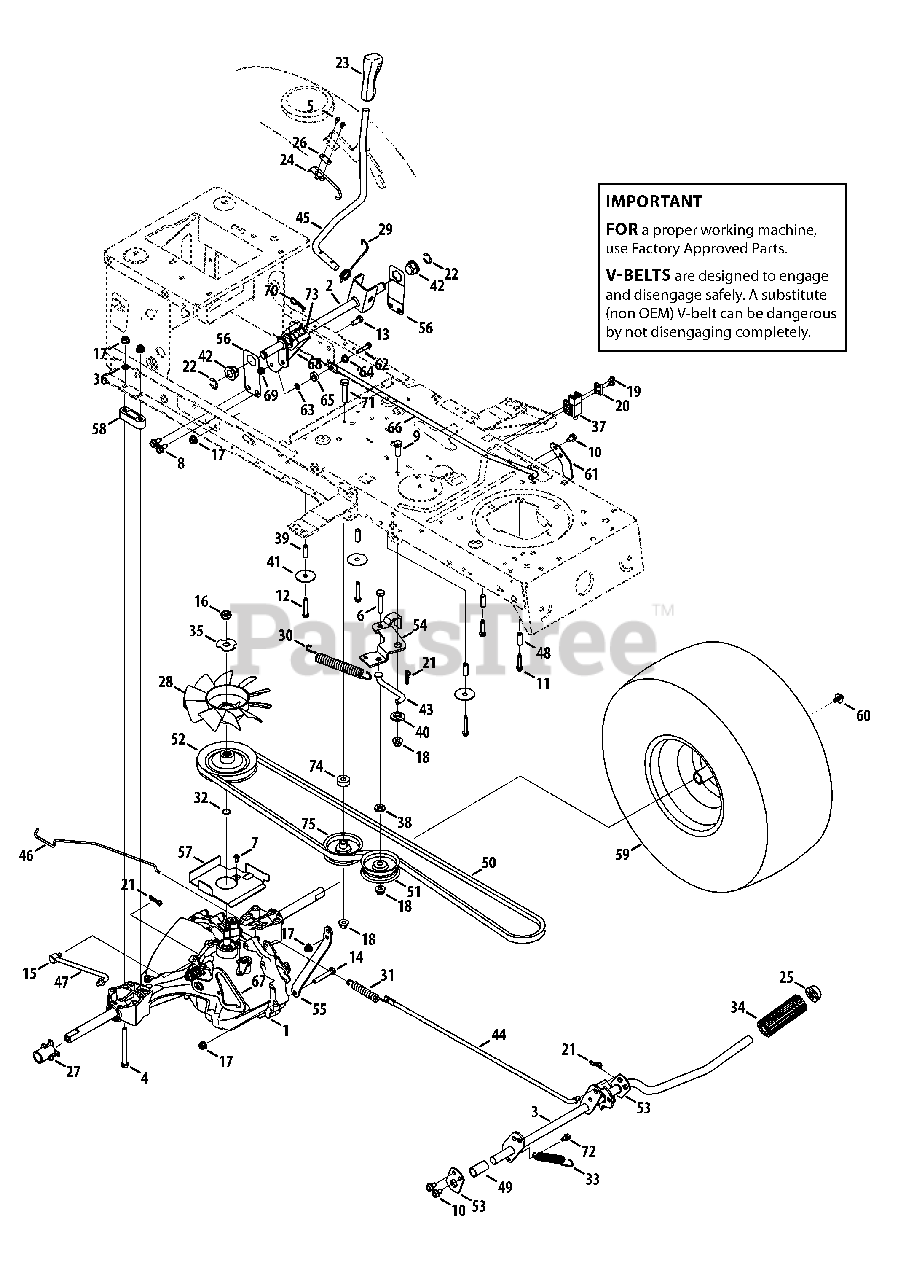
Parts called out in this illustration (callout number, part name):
1	Hydro Transmission
2	Hydro Handle Control Assembly
4	Hex Screw, 5/16-18 x 3.5
5	Screw, #8-18:0.500
6	Hex Screw, 3/8-16:1.75
7	Screw, #10-16:0.500
8	Screw, 5/16-18:.750
9	Hex Screw, 3/8-16:1.00
10	Screw, 5/16-18:0.625
11	Screw, 1/4-20:1.250
12	Screw, 1/4-20 x 1.75
13	Hex Screw, 5/16-18:.75
14	Screw, 5/16-18 x 2.00
15	Ferrule, 5/16-24 X .312 DIA.
16	Jamlock Nut, 1/2-20
17	Flangelock Nut, 5/16-18
18	Flangelock Nut, 3/8-16
20	Plate Switch
21	Cotter Pin, Bow Tie
22	E Rign, .625 DIA
23	Handle Grip
24	Hydro Spring Switch
25	Push Cap, 5/8
26	Insulator Plate Nut
27	Sleeve, .765 ID X 2.11 LG
28	Hydro Fan
29	Torsion Spring
30	Extension Spring, .75 DIA. X 6.02
31	Extension Spring, .59 OD X 4.00 LG
32	Wire Ring
33	Extension Spring, .63 DIA X 4.95 LG
34	Foot Pad, 4.0
35	Lock Washer, TRANS HYDRO
36	Lock Washer, 5/16 EXT TOOTH
37	Switch Interlock
38	Flat Washer, .407X.812X.135:HT
39	Spacer, .260 x .372 x 1.420
40	Shldr Spacer, 1.375 ID X .380 x 1.54
41	Flat Washer, .350 x 1.59 x .062
42	Hex Flange Bearing
43	Declutching Rod
44	Brake Rod
45	Hydro Control Handle
46	Hydro Bypass Rod
47	Hydro Control Rod
48	Spacer, .260 x .375 x 1.030 LG
49	Spacer, .640 ID X .76 OD X 1.60
50	V Belt, 4L SEC X 84.17
51	Flat Idler Pulley 2.75 OD
52	Input Pulley
55	Torque Bracket
56	Handle Bracket
57	Belt Support Bracket
58	Spacer, T-Axle
59	Wheel, 20 x 8 x 8, 46" Deck
60	Screw, 5/16-24 x .750
61	Stop Pedal Plate
62	Hex Screw, 1/4-20 x 1.25
63	Flat Washer, .281 x .500 x .063
64	Shoulder Spacer, .375 x .625 x .20
65	Ball Bearing, .25 x .6875 x .25
66	Hydro Rod, RTN
67	Cam Bracket, RTN
68	Pivot Bracket, RTN
69	Nut, Flange Lock, 1/4-20, GrF
70	Click Pin, .092 x 1.64 LG
71	Hex Screw, 3/8-16 x 2.00
72	Shoulder Screw, 1/4-20 x 0.50
73	Hex Flange Bearing, .628 ID
74	Spacer, .406 ID x 1.00 OD x .38
75	V Pulley 3.06 OD
